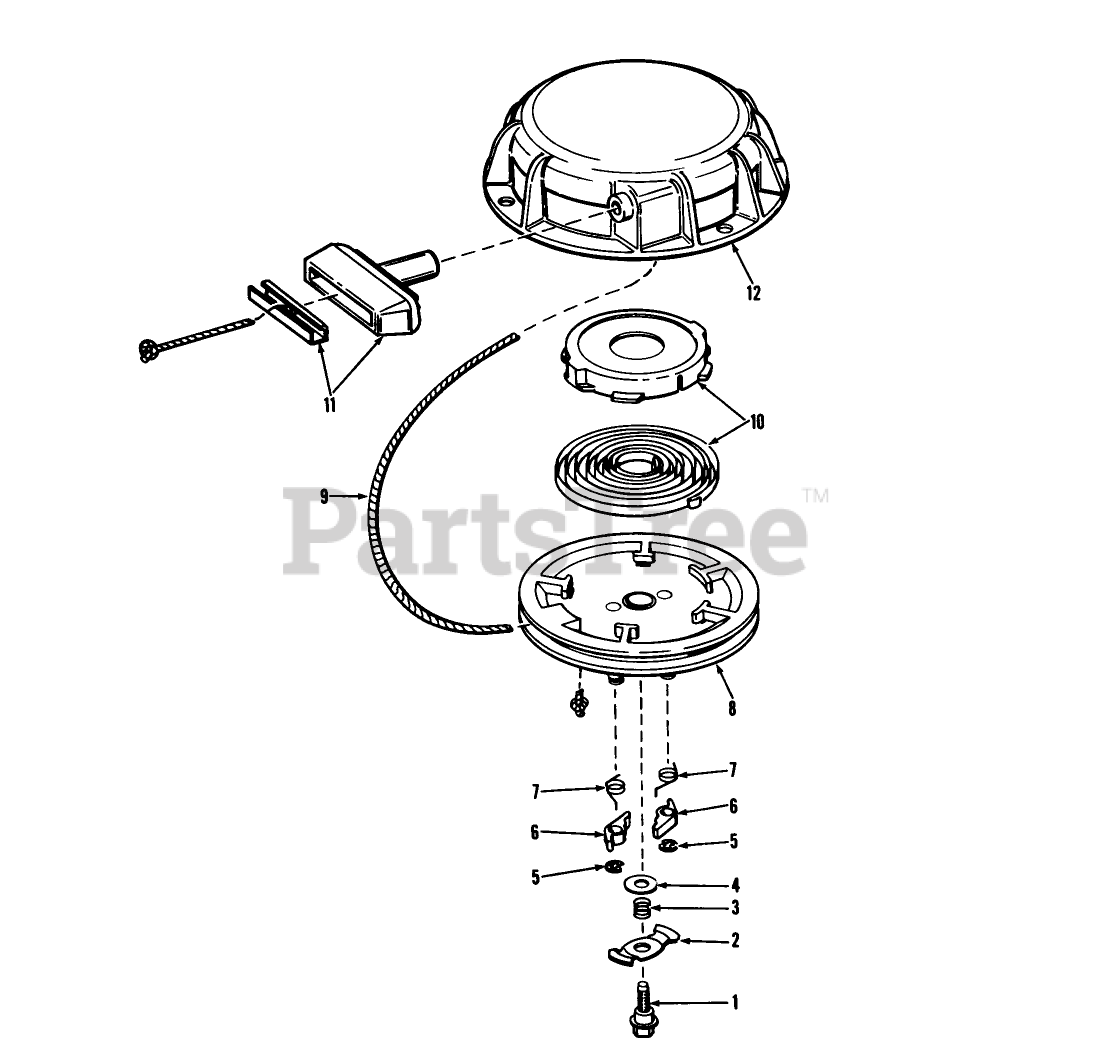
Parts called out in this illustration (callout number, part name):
1	Screw, Center
2	Cam, Dog
3	Spring, Brake
4	Washer, Brake
5	Ring, Retainer
7	Spring, Dog
8	Pulley
9	Rope-Starter
10	Spring & Keeper Assy.
11	Assy., Starter
12	Housing Assy., Starter
